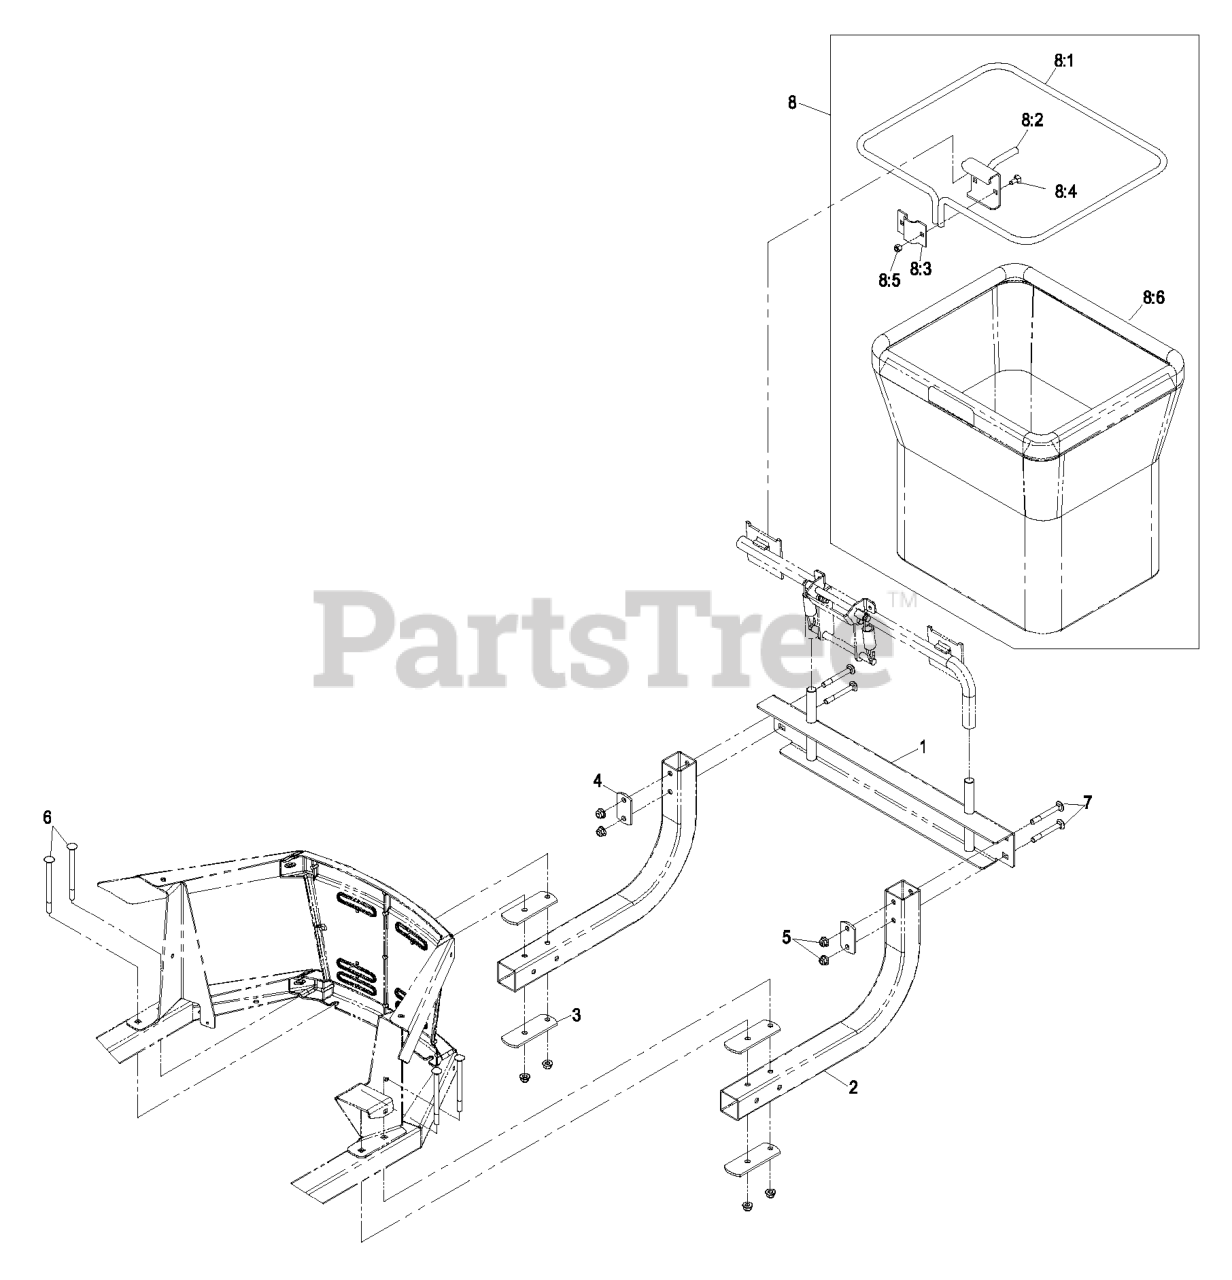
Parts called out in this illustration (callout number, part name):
2	BRACKET ASM
2:1	CUSHION-RUBBER
3	PIN-WEIGHT
4	SCREW-HSBH
5	NUT-HF, NI
6	WEIGHT,BAGGER
7	SCREW-HH
